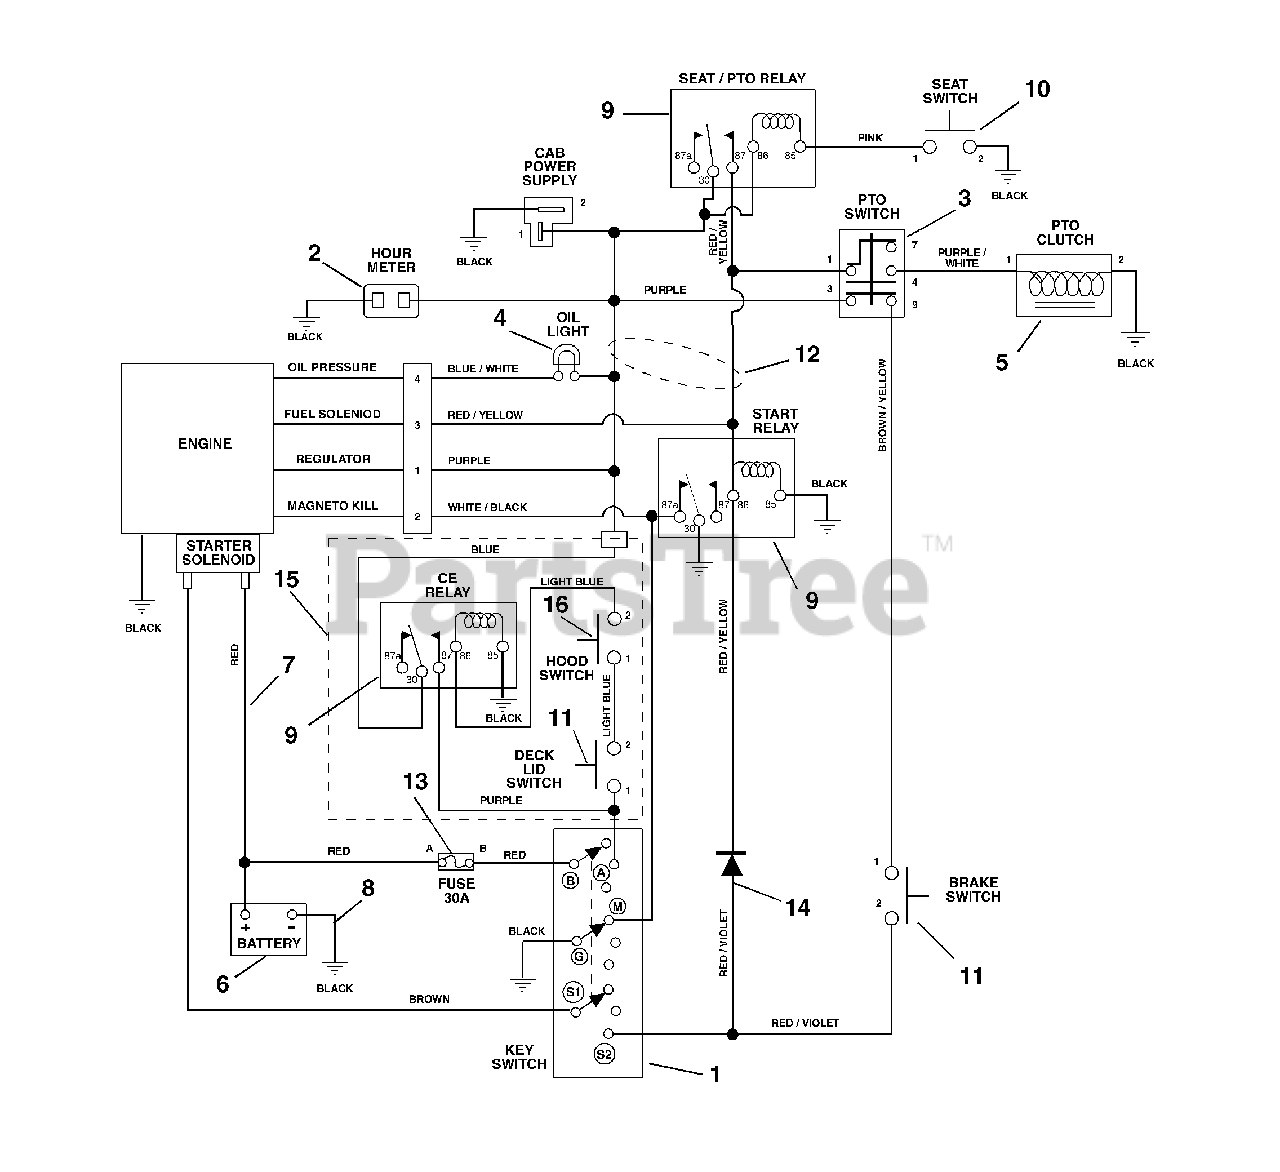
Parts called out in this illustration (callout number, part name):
1	Key Switch
2	Hour Meter
3	Switch-Clutch With Retainer Ring
4	Light-Indicator
5	Electric Clutch
6	Battery with Tube
7	Cable-Battery To Solenoid
8	Ground Cable
9	Relay
10	Seat Switch
11	Switch-Single Pole
12	Harness-Kohler
13	Fuse, 30 Amp
14	Molded Diode Plug-Black 1-Amp
15	Harness-CE Adapter
16	Switch-Single Pole (N.O.) with Cover
